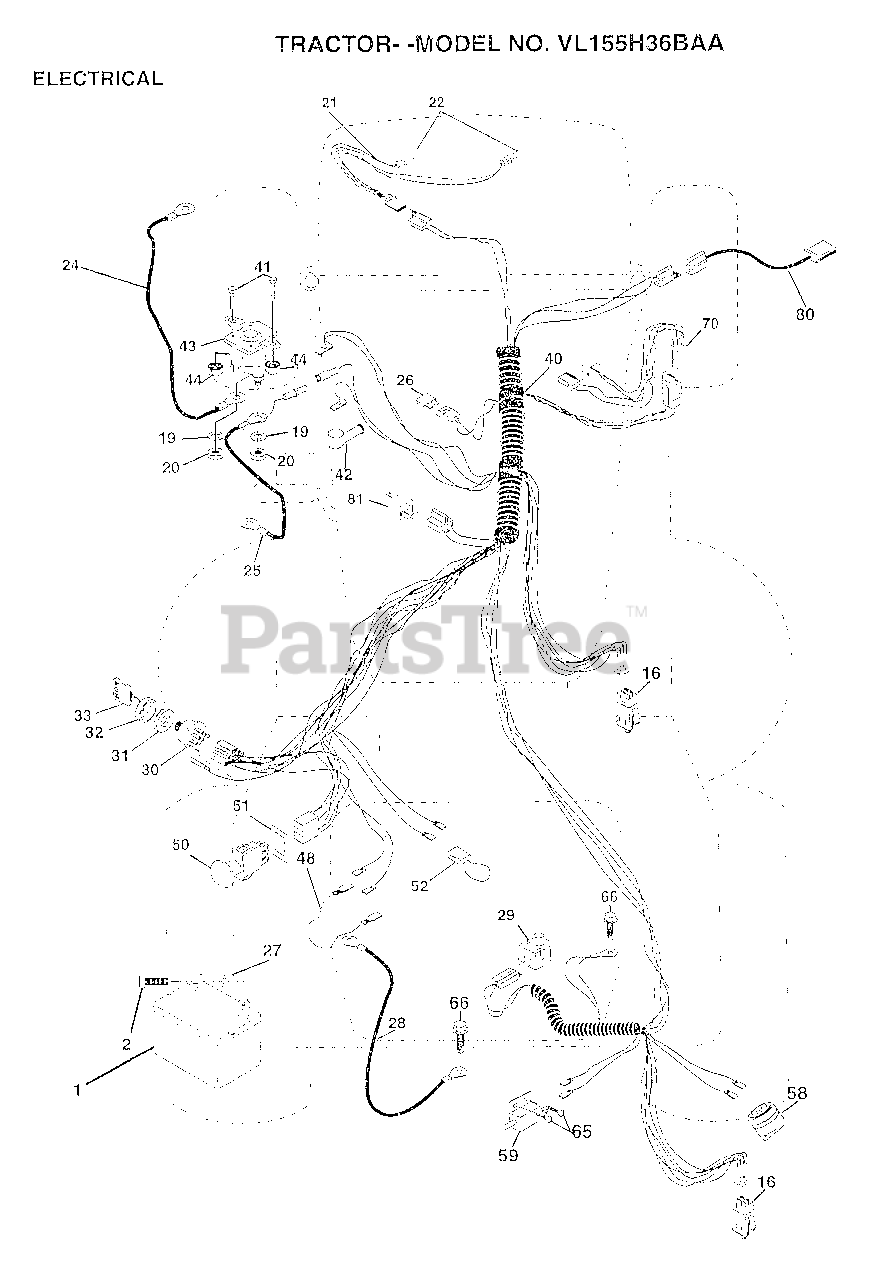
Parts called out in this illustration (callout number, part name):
2	BOLT LT
16	SWITCH INTERLOCK
20	NUT
21	HARNESS.ASM.LIGHT.W/4152J
22	HEADLAMP BULB
24	"CABLE T, BATTERY"
25	CABLE.BATTERY.CRD
26	FUSE.15 AMP
27	NUT
28	"CABLE.GRD.6GA/18""BLACK"
29	SWITCH.PLUNGER
30	SWITCH IGN 4POS
31	NUT IGNITION
32	COVER KEY SWITCH
33	KEY
40	HARNESS.IGN.CRD.ELECT
41	BOLT HXHD FIN
44	NUT HXKEP 1/4X20
48	ADAPTER AMMETER
50	PTO SWITCH.BLK
51	RING RETAIN PTO
52	PROTECTION LOOP
59	SWITCH.FBI.CRD
65	SCREW
66	SCREW LT
70	HARNESS.ENGINE
80	HARNESS.CLUT.EVX.
81	RELAY ASSY T
